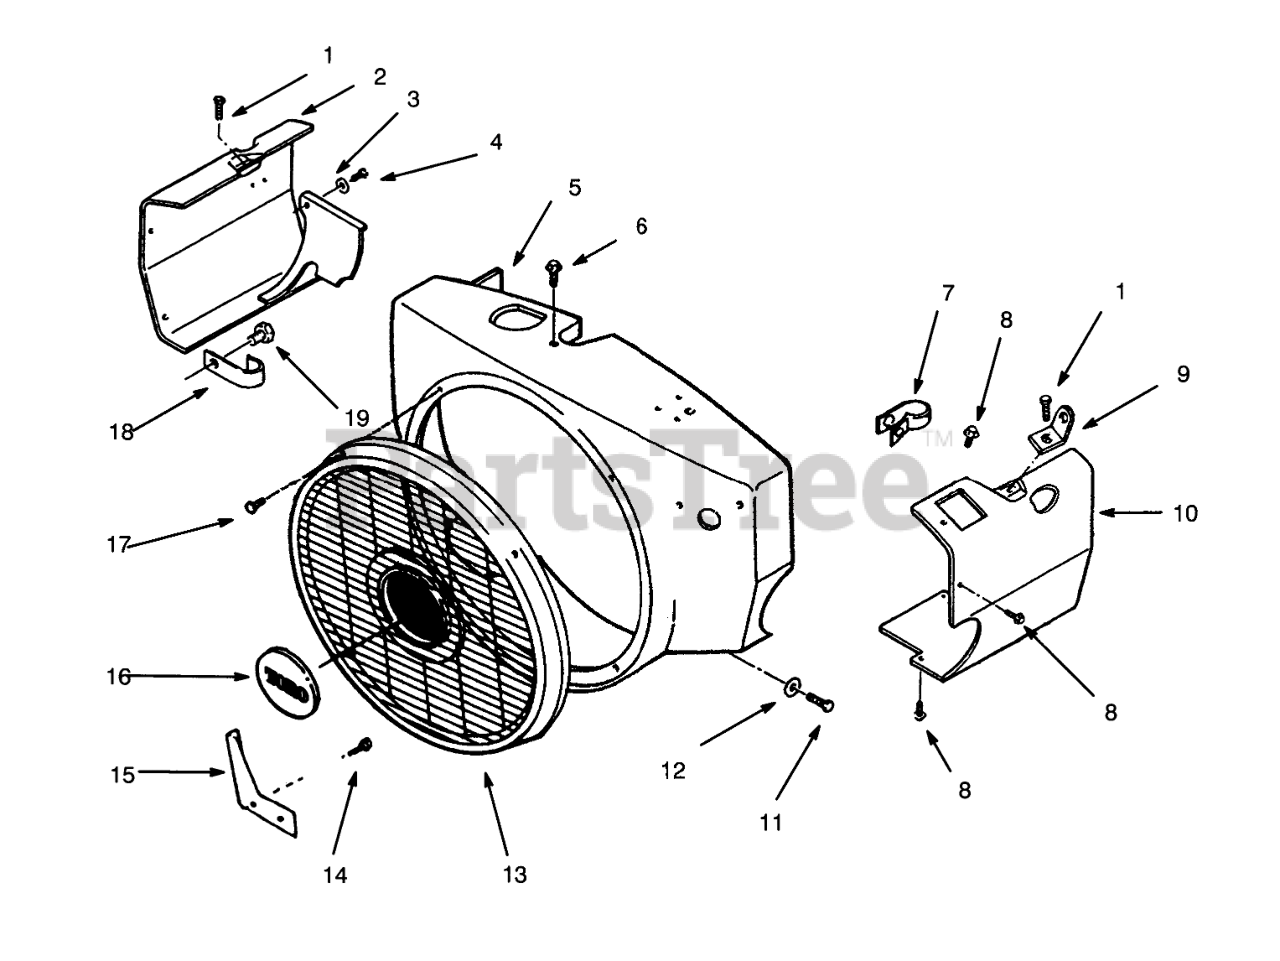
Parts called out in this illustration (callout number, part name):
1	SCREW-HWH
2	LH AIR CYLINDER HSG
3	Bolt
4	SCREW-HH
5	HOUSING
6	HEX HD CAPSCREW
7	Clamp
8	Bolt
9	Bracket-Lifting
10	RH AIR CYLINDER HSG
11	Bolt
12	Washer
13	GUARD-STATIONARY
14	SCREW - THREAD CUTTING
15	BRACKET
16	NAME-PLATE TORO LOGO
17	SCREW-PAN HEAD
18	Clip
19	SCREW-HWH
